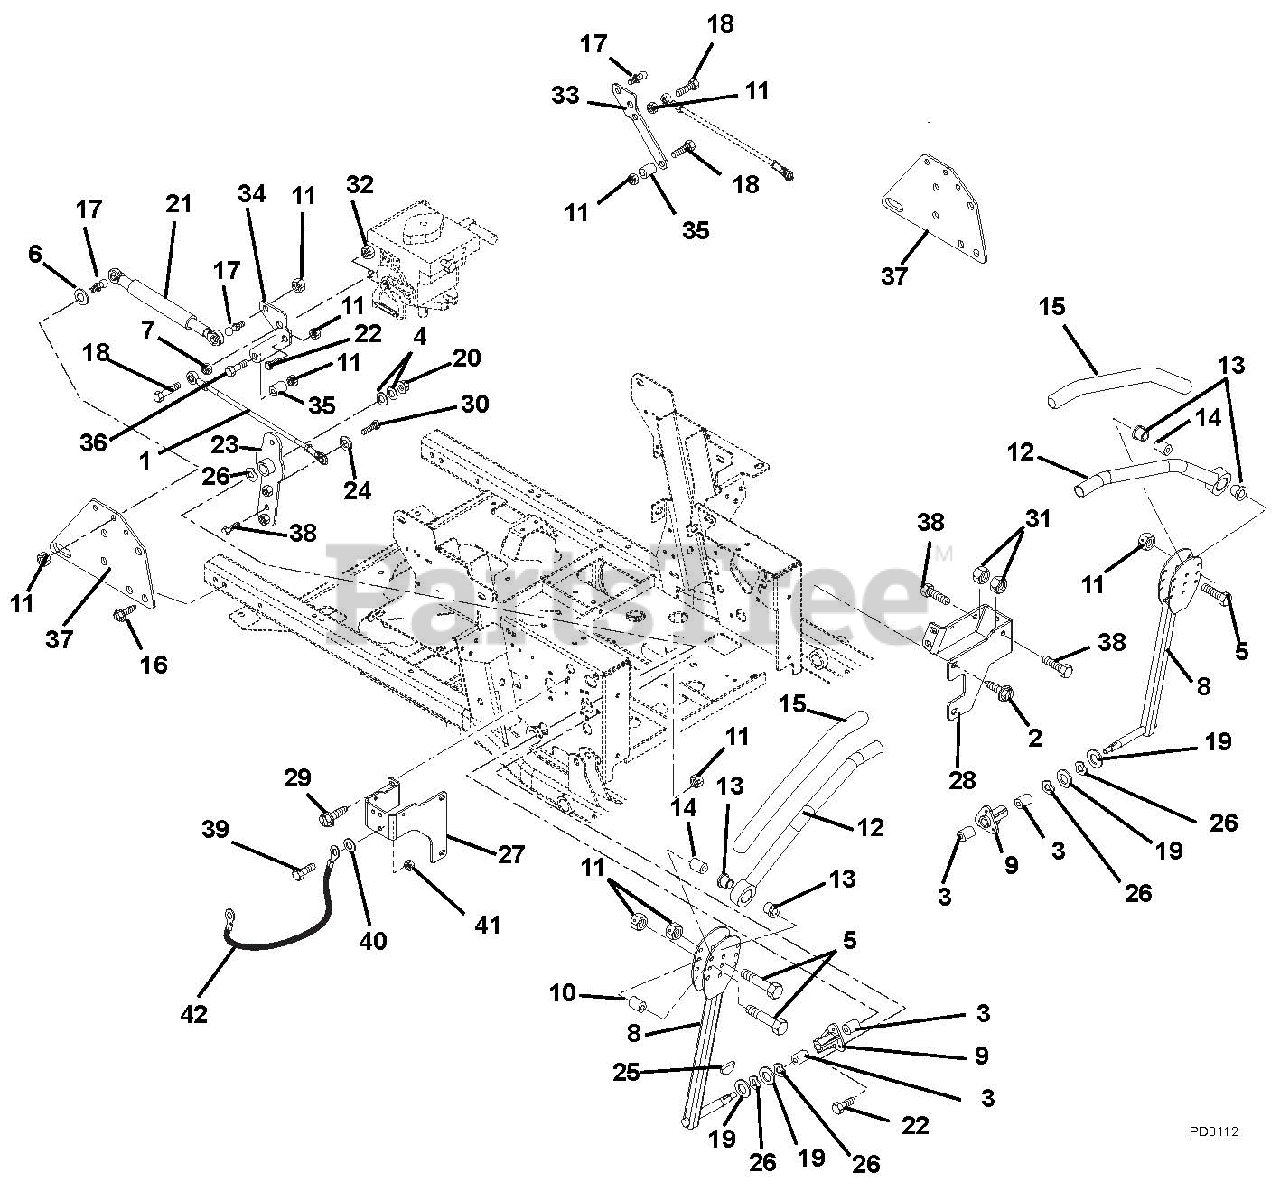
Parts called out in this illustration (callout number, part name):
1	Assembly, Steering Rod .38 Rod x 7.60
2	Screw, Tapping .38-16 x .75 Hex Washer Head
3	Bushing .625 x .75 x .50
4	Washer, Flat Steel .403 x .812 x .065
5	Bolt, Hex .31-18 x 1.75 Grade 5
6	Washer, Flat Steel .344 x .688 x .065
7	Nut, Hex .38-16
8	Control Arm
9	Bushing, Flange
10	Eccentric
11	Nut, Locking Top Flange .31-18
12	Handle Weldment Left-Hand
12	Handle Weldment Right-Hand
13	Bushing, Flange Nylon .762 x 1.48 x .44
15	Grip, Handlebar
16	Screw, Tapping .31-18 x .50 Hex Washer Head
17	Stud, Ball
18	Bolt, Hex .38-16 x 1.50 Grade 5
19	Washer, Flat Steel .63 x 1.005 x .062
20	Nut, Locking Top Flange .38-16
21	Damper, Control
22	Bolt, Hex .31-18 x .75 Grade 5
23	Weldment, Pivot Arm
24	Washer, Locking .38 x .094 Regular
25	Key, Woodruff .13 x .63
26	Washer, Wave
27	Stop, Steering Right Hand
28	Stop, Steering Left Hand
29	Screw, Tapping .38-16 x .50 Hex Washer Head
30	Bolt, Hex .38-16 x 1.25 Grade 5
31	Nut, Hex Jam .375-16
32	Nut, Locking Center .38-16
33	Bracket, Left Hand
34	Bracket, Right Hand
35	Spacer .318 x .43 x .375
36	Bolt, Hex .31-18 x 1.25 Grade 5
37	Bracket, Damper
38	Bolt-Hex .375-16 x 1.75 Full Thread
39	Bolt-Hex .25-20 x .75 Grade 5
40	Washer, Flat Steel .265 x .50 x .087
41	Nut, Locking Top Flange .25-20
42	Cable, Hood
